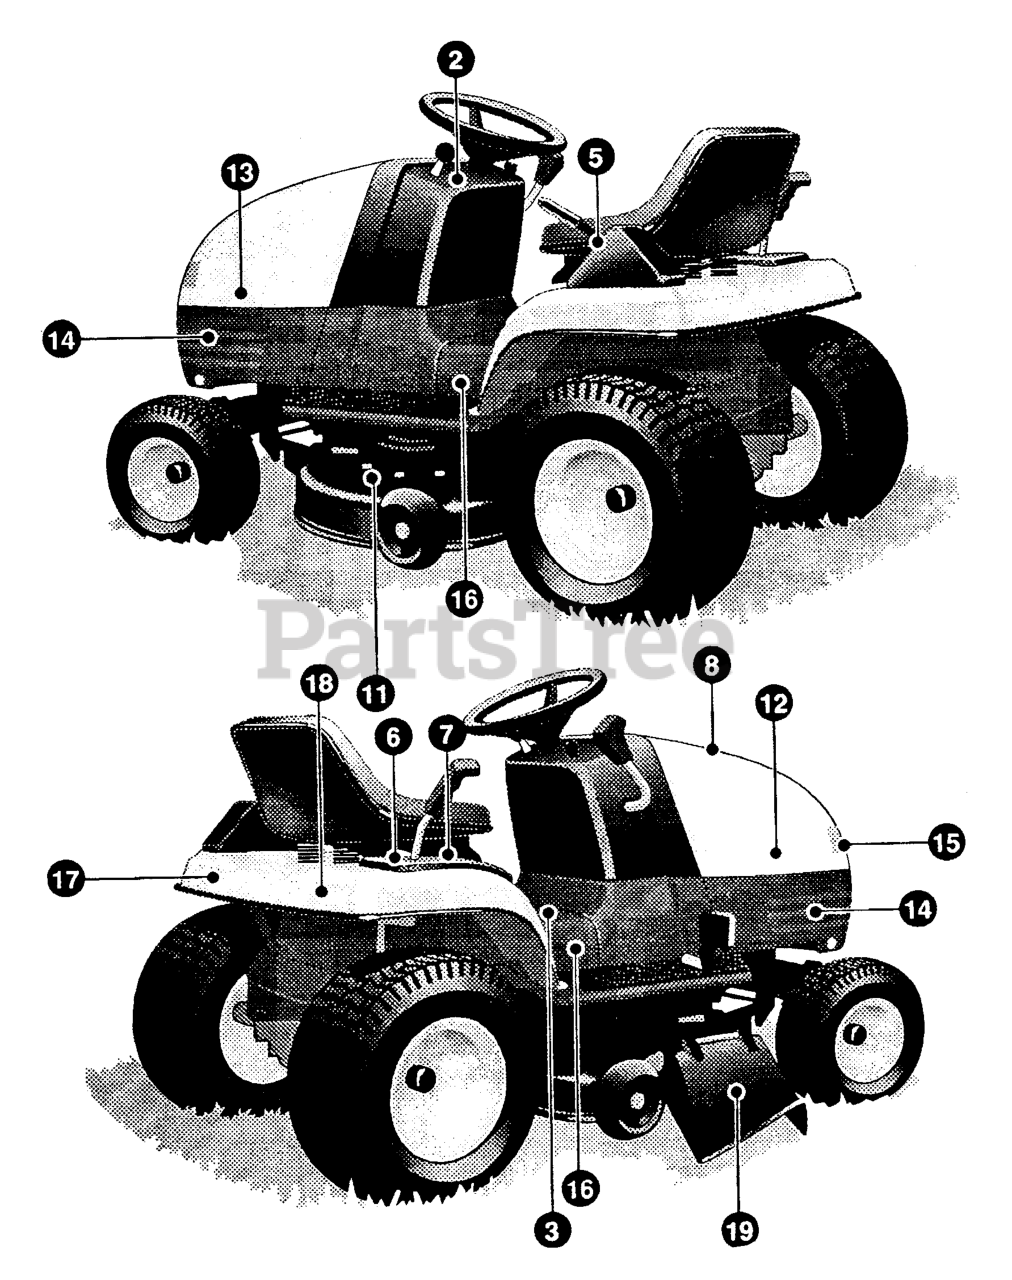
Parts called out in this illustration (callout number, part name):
2	DECAL, DASH
3	DECAL, CAUTION CONSOLE TOP
5	DECAL, HEIGHT ADJUST
6	DECAL, SHIFT REV/NEUTRAL
7	DECAL, SHIFTER POSITION
11	DECAL, 3-N-1 MOWER DECK
12	DECAL, PERFORMANCE HOOD
13	DECAL, PERFORMANCE HOOD
14	DECAL, KOHLER
15	DECAL, NOMA GRILLE
16	DECAL, 43" CONSOLE
17	DECAL, PERFORMANCE FENDER
18	DECAL, FENDER AWS
19	DECAL, MULCHING KIT INSTALLED
